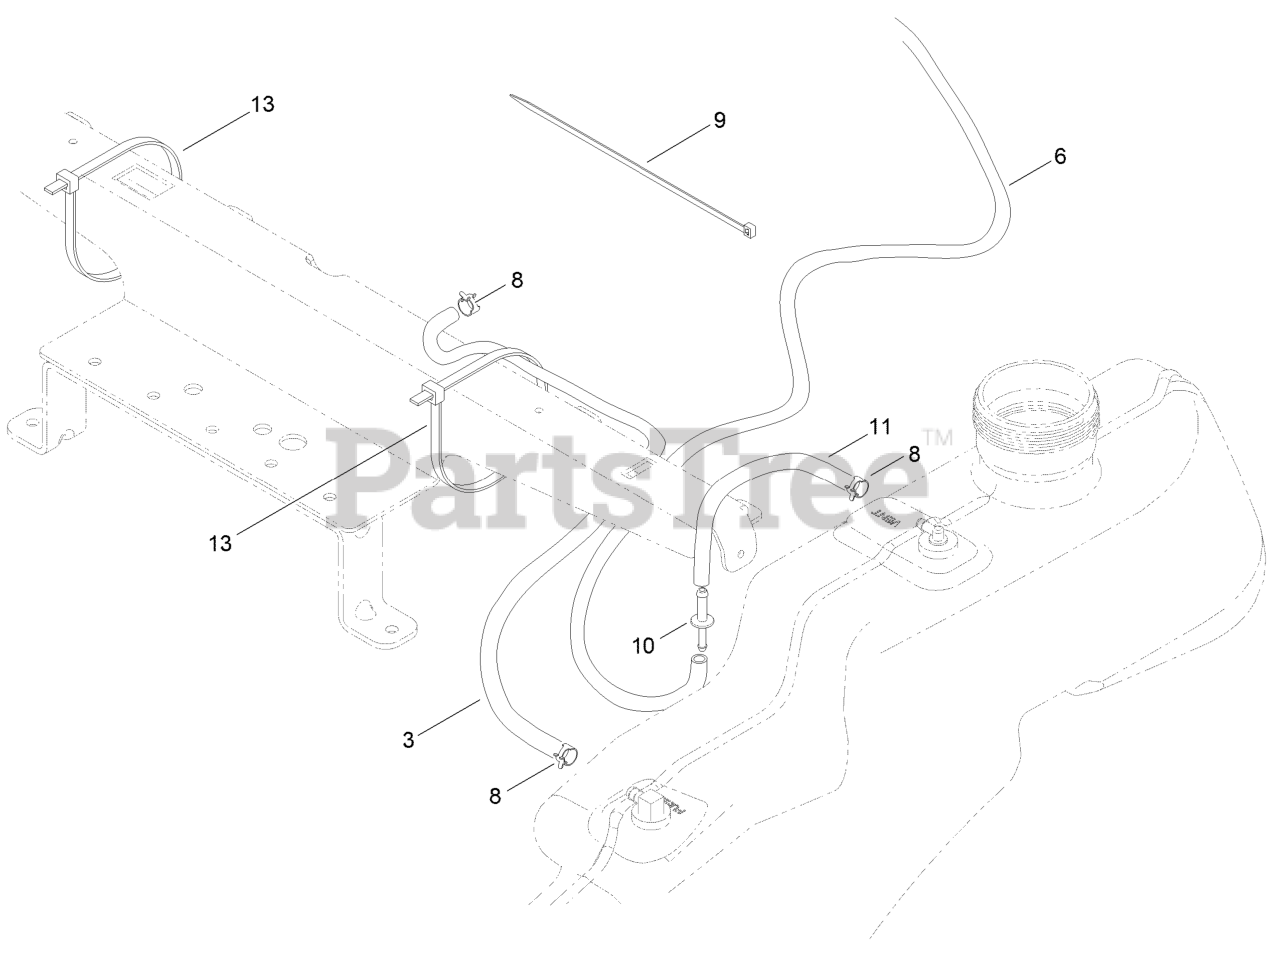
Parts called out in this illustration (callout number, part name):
3	HOSE-FUEL
6	HOSE-FUEL
8	CLAMP-HOSE
9	TIE-CABLE
10	ADAPTOR-ORIFICE
11	HOSE-FUEL
13	TIE-CABLE
